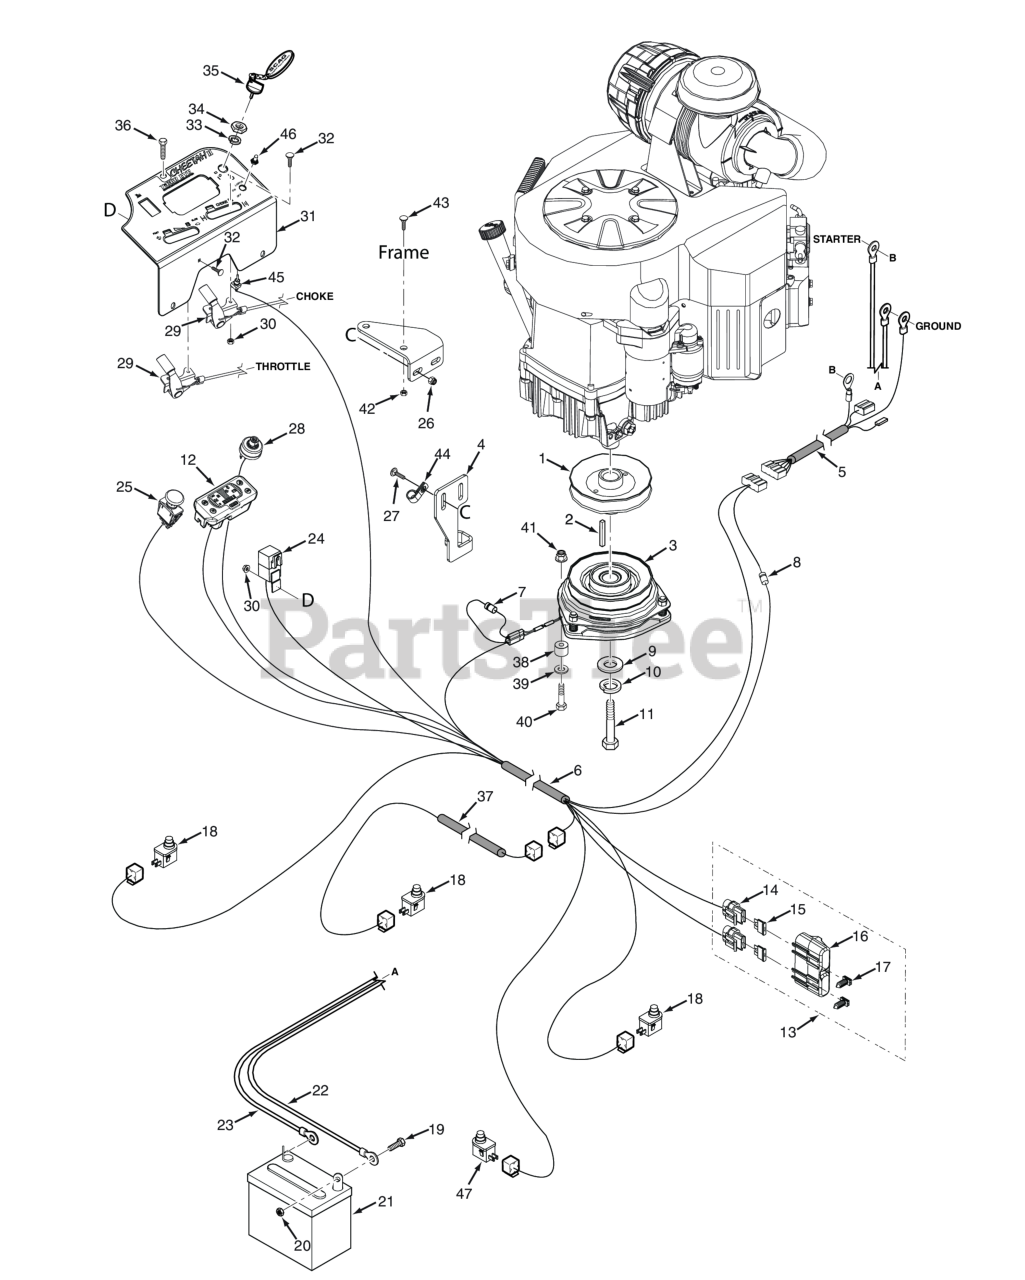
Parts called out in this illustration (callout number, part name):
1	Pulley, 5.80" Dia. - 1.125 Bore
2	Key, 1/4 x 1/4 x 3-1/4�
3	Electric Clutch w/Tag - GT-5 (ECV860, ECV940)
4	Bracket, Anti-Rotation
5	Wire Harness Adapter, Kawasaki FX & FT
6	Wire Harness, SCZII
7	Diode, 600V 6 Amp
8	Decal, Forward Speed Selector
9	Flatwasher, 7/16-.469 x 1.75 x .25 (48, 52)
10	Lockwasher, 7/16� Spring
11	Bolt, Hex Head 7/16-20 x 2-1/4" w/Patch (Kawasaki)
12	Tiger Eye, Cluster Gauge
13	Double Fuse Assy.
14	Fuse Holder Assembly
15	FUSE, 20 AMP BLADE TYPE AUTOMOTIVE
16	Cover, Sealed Double
17	Clip, Fuse Holder
18	Switch, Interlock, Normally Open
19	Bolt, Hex Head 1/4-20 x .5" Battery, (Not Available Through Scag)
20	Nut, 1/4 - 20 Hex
21	Battery
22	Battery Cable, 27" Black (35BV & 37BV-EFI) - Briggs & Stratton
23	Battery Cable, 25" Red (Kawasaki)
24	Relay, 12V 40 AMP Standard
25	Switch, PTO - 10 Amp
26	Nut, Flange Head Elastic Stop 5/16-18
27	Bolt, Carriage 5/16-18x1" (large frame units only)
28	KEY SWITCH(INCLUDES MOUNTING HARDWARE)
29	Control Cable (Kawasaki FX921 Throttle & Choke Cable)
30	Nut, Elastic Stop #10-24
31	Instrument Panel w/Decal
32	Bolt, Carriage #10-24 x 1/2"
33	LOCK WASHER, 5/8" INTERNAL TOOTH
34	Nut, 5/8-32 Special
35	Key, Assembly w/Fob
36	CAP SCREW, 1/4-20 X 1/2" SERRATED FLANGE HEX
37	Wire Harness, Operator Platform -SCZ
38	Bushing, UHMW
39	Flatwasher, 5/16-.375 x .875 x .083 (35BV & 37BV-EFI)
40	Bolt, Hex Head 5/16-18 x 1-1/2" (Right Front Engine Mounting, Briggs and Kohler Only)
41	HEX NUT, ELASTIC STOP LOCK, 5/16-18
42	NUT, 3/8-16 SERRATED FLANGE HEX HEAD
43	Carriage Bolt, 3/8-16 x 1.0"
44	Clamp, Cable 1/2" I.D.
45	SWITCH, ON / OFF
46	BOOT, SWITCH
47	Switch, N/C
